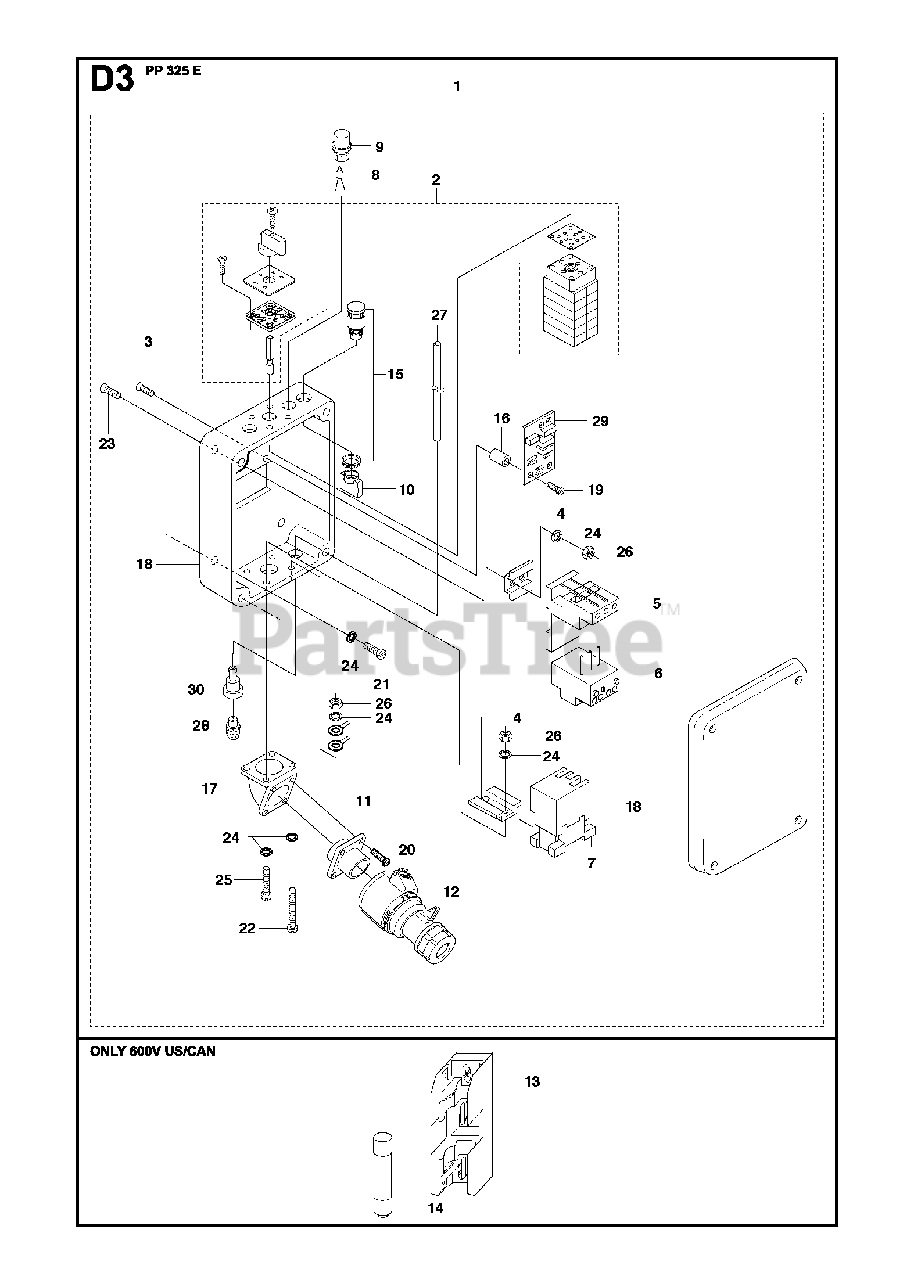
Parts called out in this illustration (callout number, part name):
1	/PP325E230/400 V, NOR
1	ELECTRIC BOX200 V, JAP
1	ELECTRIC BOX600 V,US/CAN
12	EXTENSION JOINT400Ð440 V
19	SCREW SLCHM
22	SCREW SLCHM
24	WASHER
